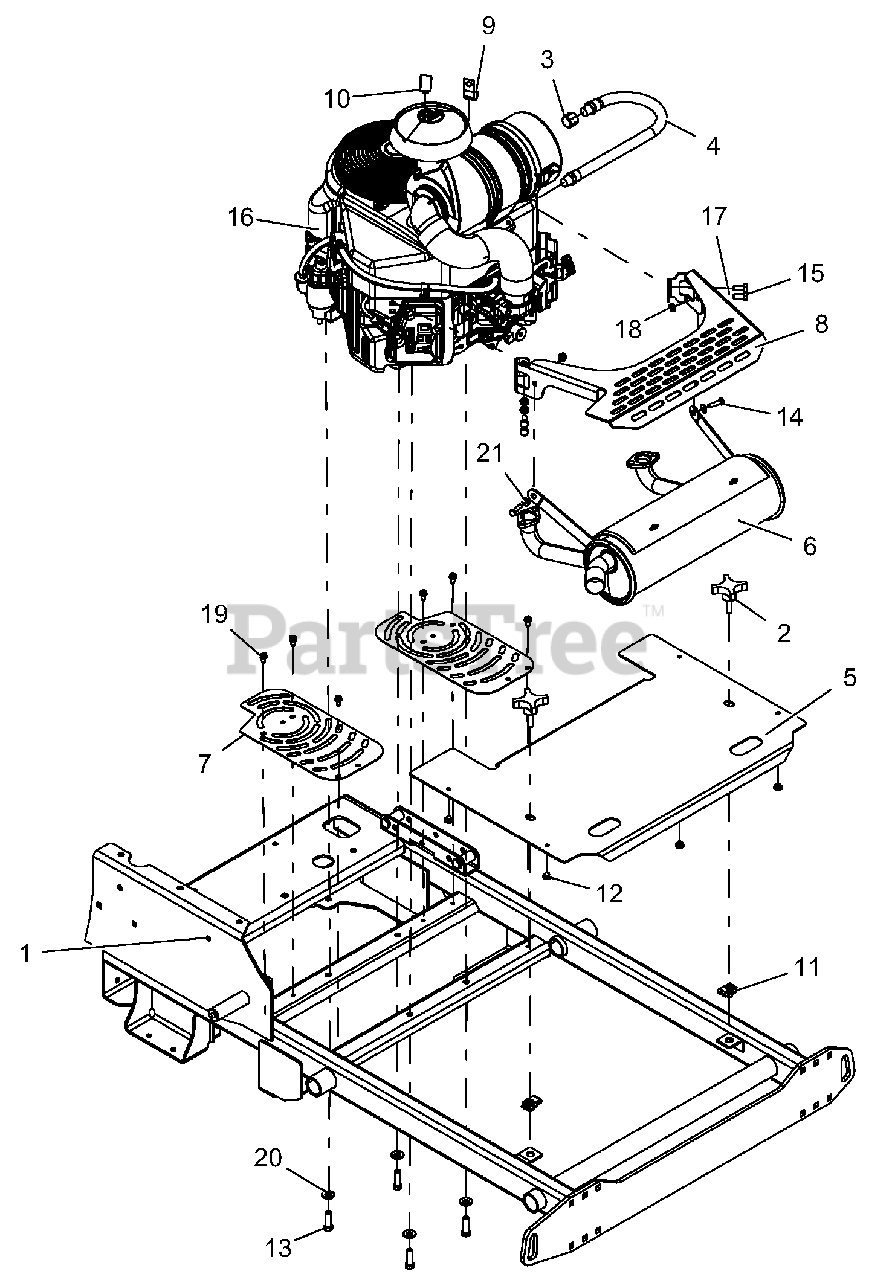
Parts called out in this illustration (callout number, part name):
1	WLDMT, FRAME PROSTANCE
2	KNOB, 3/8 x 1.25 - 4 PRONG
3	PIPE, CAP 3/8 NPT FEMALE
4	DRAIN, M20 OIL
5	SHIELD, FRONT PRO-STANCE - RED
6	EXHAUST, KAWASAKI PROSTANCE
7	GUARD, FAN
8	SHIELD, MUFFLER - BLACK
10	CLAMP, CUSHIONED STEEL REV
11	NUT, RTNR .375-16 x .37
12	BUMPER GROMMET .125 x .25 REV
13	BLT-HEX .38-16 x 1.25 GR5 YWZC NYTORQ
14	BLT-HEX .25-20 x 1.00 GR5 YWZC
15	@BLT-HEX M8-1.25 x 20 YWZC
16	ENGINE, KAWASAKI FX730
17	WSHR-LK .31 x .078 REG YWZC
18	NUT-LK-NYL-FLG .25-20 YWZC
19	SCR-TAP .25-20 x .50 HWH TR YWZ
20	WSHR, 3/8" SPRING DISC
21	WSHR-FL-STL .281 x .62 x .065 YWZC
